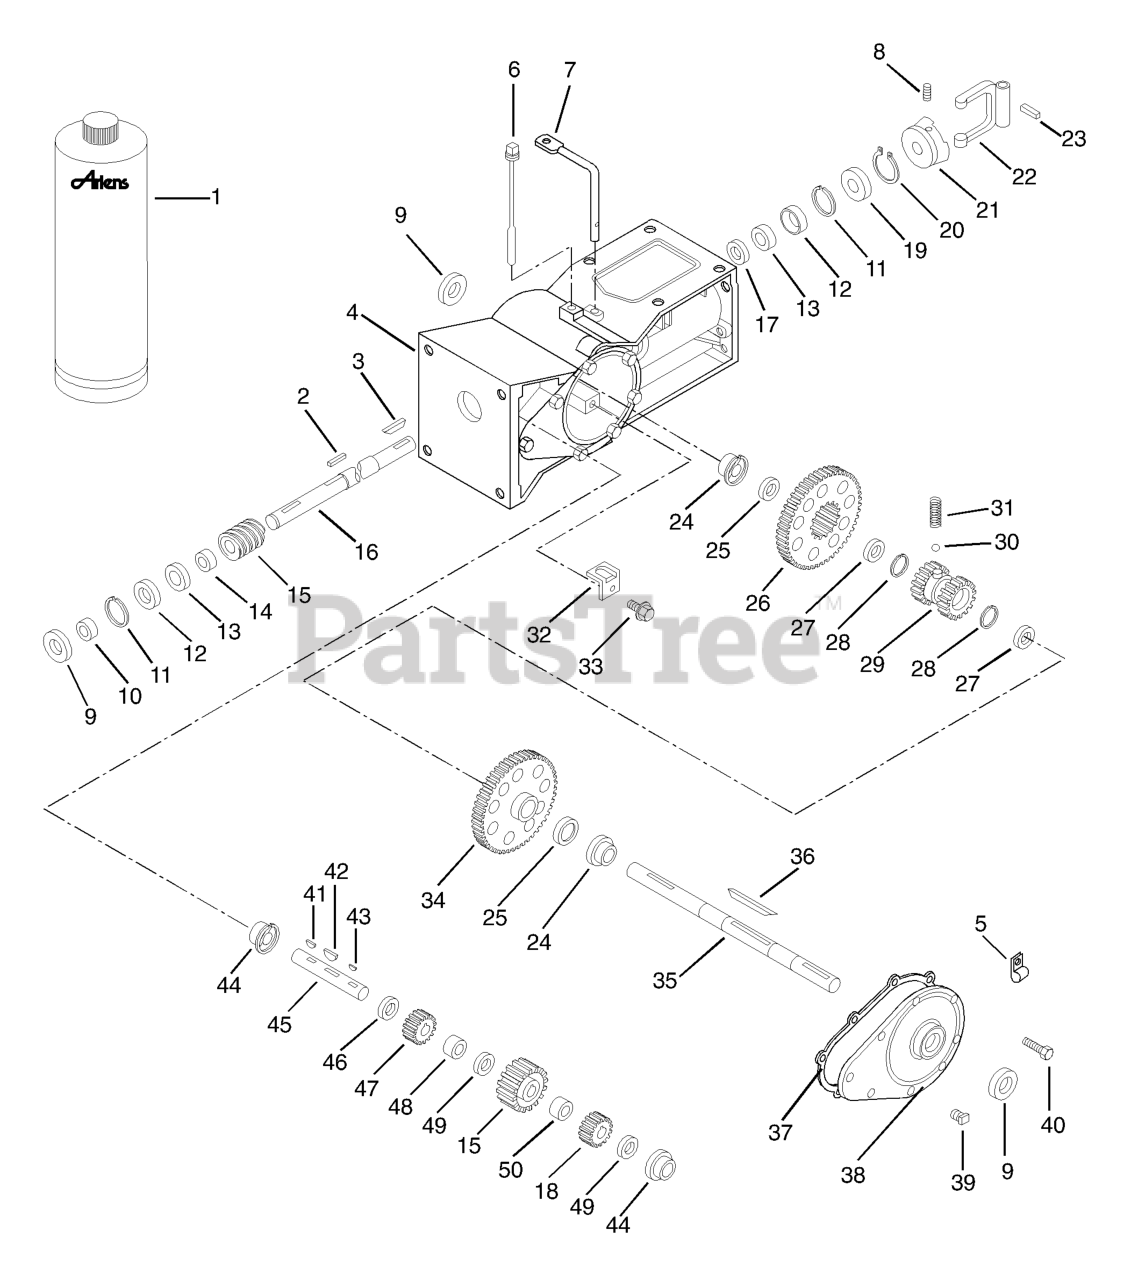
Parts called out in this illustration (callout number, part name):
1	ARIENS 16 OZ.BOTTLE OF L2 LUBE
2	KEY-SQ .188X1.0X.188 SAE 8630
3	KEY-FTHR .188X1.25X.187 SAE
4	TRANSMISSION HOUSING
5	CLAMP, CUSHIONED STEEL
6	DIP STICK
7	HIGH-LOW SHIFT LEVER
8	SCR-SET .31-18X.38 SKHCUPDL
9	SEAL 1.000X1.785X.250
10	SPACER BUSHING .99 X .75 X .50
11	RG-RTNG-INT 1.781X.052
12	BRG-CUP 1.781X.475
13	BRG-CONE .750X.61
14	BSHG, SPCR .755X1.12X.50 PM
15	WORM AND WORM GEAR
16	WORM SHAFT
17	WSHR-FL-STL .755X1.375X.125
18	LOW PINION
19	SEAL .750X1.781X.250
20	RG-RTNG-EXT .689X.078
21	TILLER DRIVING JAW
22	SHIFT YOKE
23	PIN-ROLL .250X1.00
24	BSHG-FLG 1.000X1.25X1.000X1.50
25	WSHR-HRD-THRS 1.007X1.542X.062
26	HIGH GEAR ASSY
28	RG-RTNG-EXT 1.00X.078
29	CLUTCH HUB
30	STEEL BALL
31	SG-COMP .047X.31X.593 WLD11
32	RETAINER CLIP
33	SCR-TAP 10-24X.75 HWH TR YWZC
34	LOW GEAR
35	AXLE SHAFT
36	KEY-FTHR .25X2.75X.25 SAE1035
38	TRANSMISSION COVER
39	PIPE PLUG
40	@SCR-TAP .31-18X.75 HWH TR YWZ
41	KEY-WDRF .188X.625X.31 SAE9MOD
42	KEY-WDRF .25X.687X.375
43	KEY-WDRF .188X.75X.313 SAE 9
44	BSHG-FLG .750X1.000X.750X1.250
45	SHAFT, PINION
46	WSHR-HDND-THRST .760X1.25X.094
47	HIGH PINION
48	SPACER 1.25 X .75 X .75
49	WSHR-HDND-THRST .758X1.23X.031
50	SPACER 1.25 X .75 X .75
